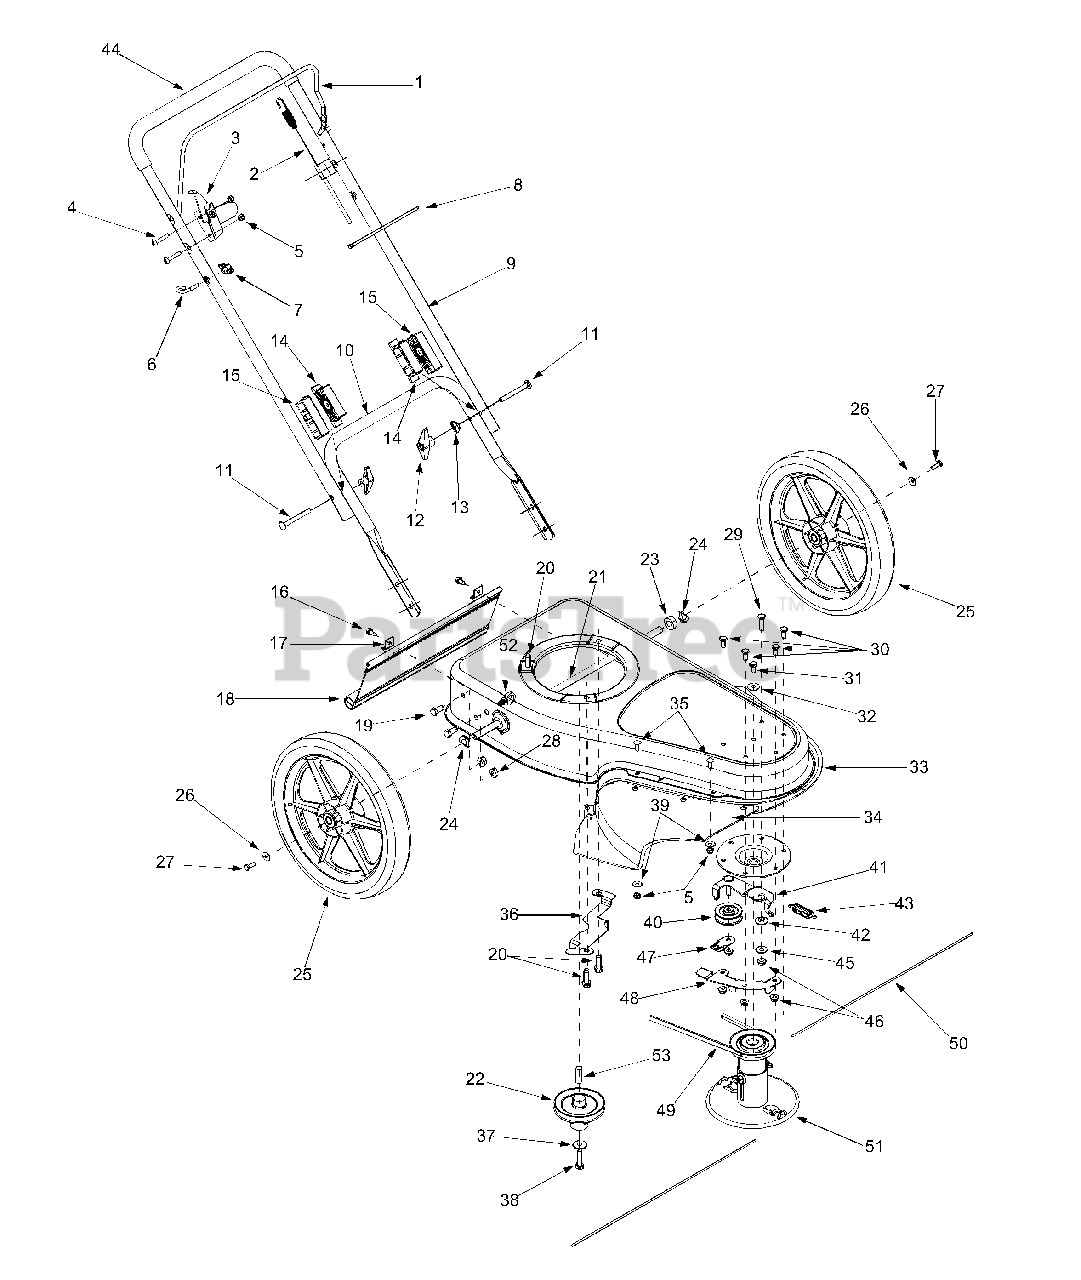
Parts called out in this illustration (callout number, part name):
2	Engagement Cable
3	Control Lock Bracket
4	Machine Screw 1/4-20 x 1.50
5	Hex Lock Nut 1/4-20
6	Eye Bolt 1/4-20
8	Cable Tie
13	Shoulder Washer .320 ID x .93 OD
14	Lower Handle Connector
15	Upper Handle Connector
16	Hex Washer Screw 1/4-14 x .625
17	Trail Shield Clip
18	Trail Shield
19	Hex Cap Screw 3/8-16 x .750
20	Hex Washer Screw 3/8-16 x 1.25
21	Trimmer Axle
22	Flywheel Pulley
23	Spacer .51 ID x 1.0 OD
24	Spacer Washer .501 ID x 1.0 OD
25	Wheel Assembly
26	Bell Washer .265 ID x .75 OD
27	Hex Cap Screw 1/4-20 x .75
28	Flange Lock Nut 3/8-16
29	Screw 5/16-18 x 1.25
30	Screw 5/16-18 x .75
31	Hex Cap Screw 5/16-24 x .625
32	Bell Washer .325 ID x .930 OD
35	Hex Carriage Screw 1/4-20 x .75
38	Hex Cap Screw 3/8-24 x 1.50
39	Flat Washer .28 ID x .74 OD
40	Idler Pulley
41	Idler Bracket Assembly
42	Idler Spacer
43	Extension Spring .50 Dia x 1.88 Lg
44	Handle Grip
45	Flat Washer
46	Flange Lock Nut 5/16-18
49	V-Belt
50	Trimmer Line .155 Dia
51	Spindle Assembly
52	Cable Retainer Clip
